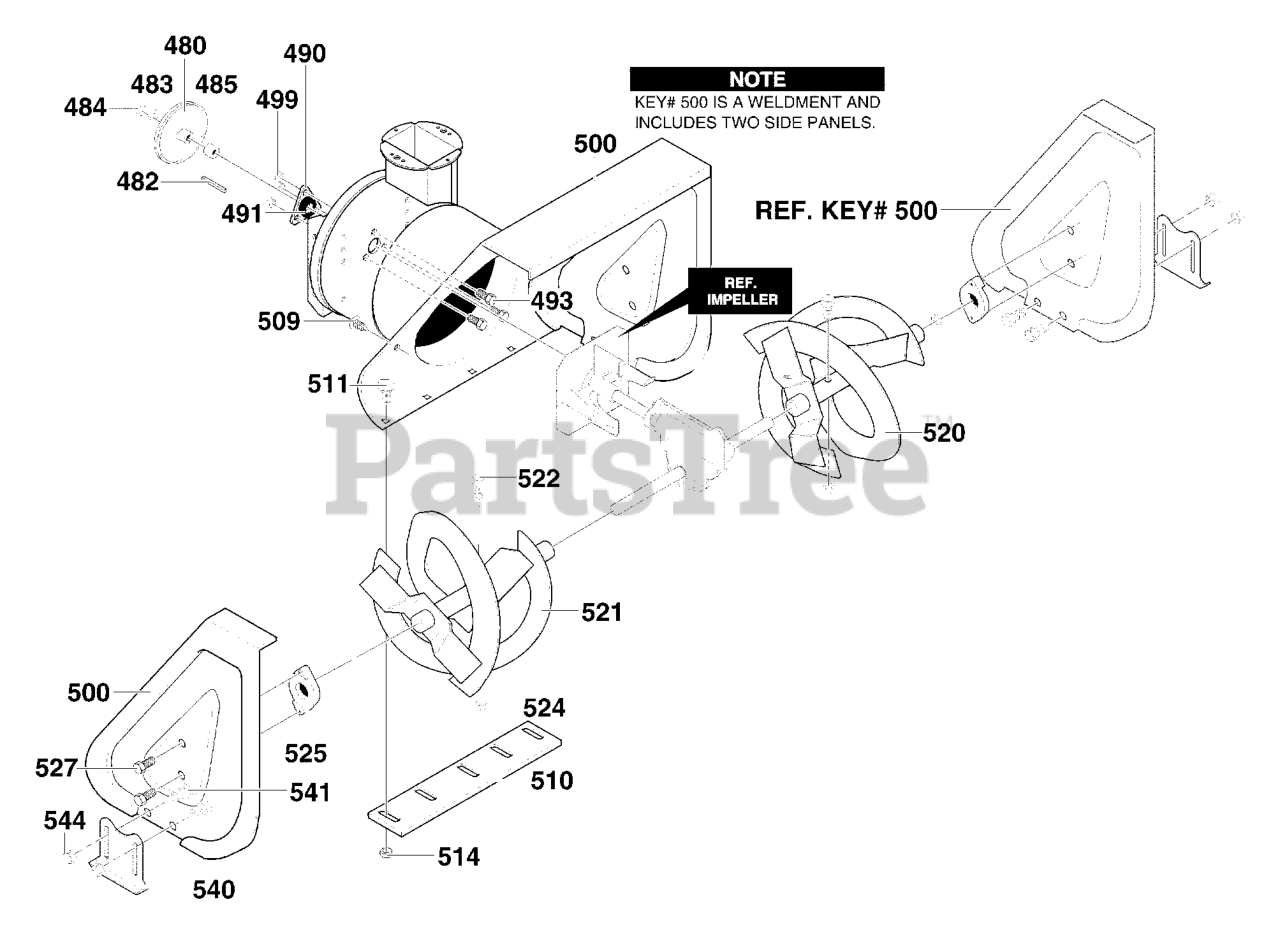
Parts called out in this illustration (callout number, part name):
480	PULLEY, V4L
482	KEY, SQUARE
483	WASHER, FLAT .53X1.00X.063
484	NUT, 1/2-20 REGHEXCTRLK
485	SPACER, SLEEVE
490	RETAINER, BALL
491	BEARING, BALL
493	SCREW, 5/16-18 x 0.75
499	NUT, 5/16-18
500	HOUSING, ASSY
509	PLUG, CHRISTMAS TREE
510	SCRAPER BLADE
511	BOLT, 1/4-20X.75 CARR.
514	NUT, 5/16-18 HEXWDFLLK WHIZ
520	AUGER, LH
521	AUGER, RH
522	BOLT
524	NUT, 5/16-18 REGHXCTRLK
525	BEARING, AUGER SHAFT
527	SCREW, 5/16-18 x 0.75
540	SKID, HEIGHT ADJUST
541	BOLT, 5/16-18X .75
544	NUT, 5/16-18 REGHEX
545	STIFFENER
546	BOLT, 5/16-18
547	FLATWASHER
549	NUT 5/16-18
